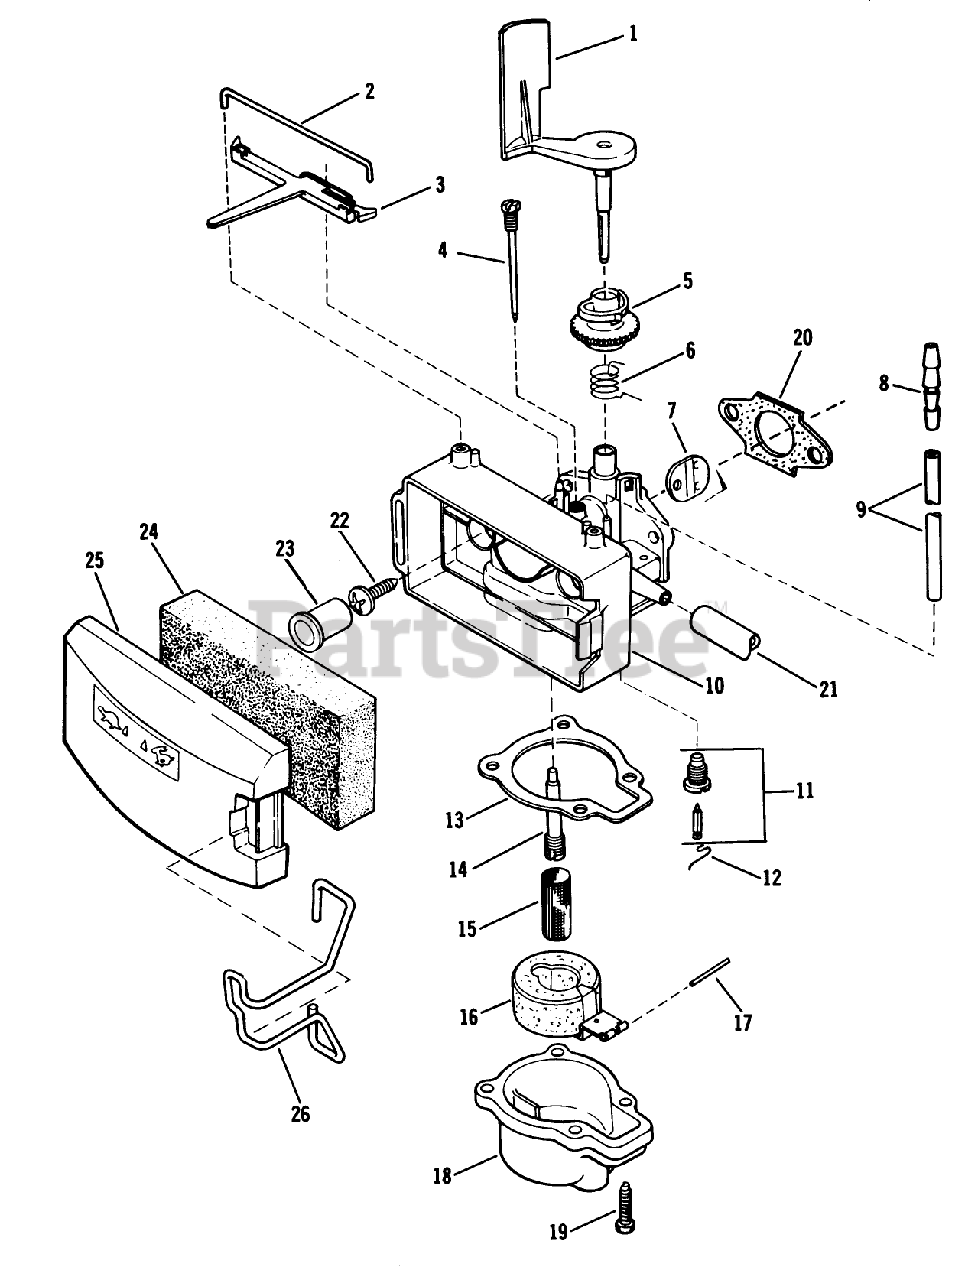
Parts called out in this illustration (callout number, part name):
2	RETAINER
3	LEVER S
4	NEEDLE ADJ. AY S
5	COLLAR-ADJUST, AIRVANE
6	SPRING,THROTTLE S
7	DISC S
8	REDUCER-CONNECTOR
9	TUBING S
10	CARB BODY S
15	FILTER-FUEL VS
19	SCREW-HH
20	GASKET CARB S
21	GAS LINE
22	SCREW
26	RETAINER-COVER, FILTER
